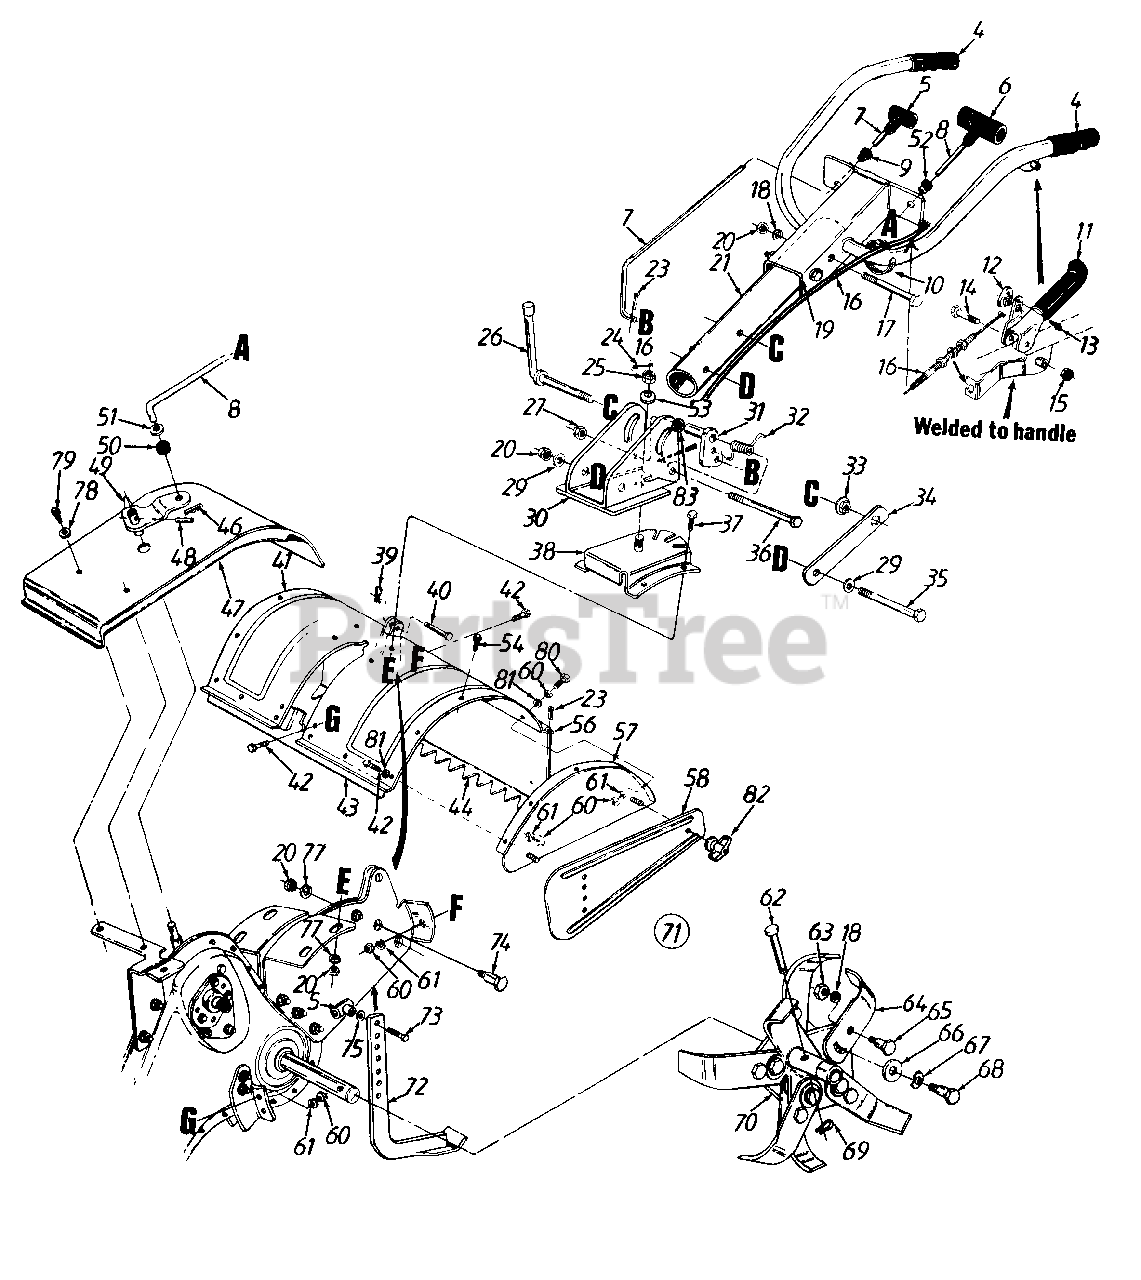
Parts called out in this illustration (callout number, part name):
4	Handle Grip
5	Small "T" Knob
6	Large "T" Knob
7	Clutch Rod
8	Control Rod 37" Lg.
9	Snap On Bushing 3/8" Dia.
10	Cable Tie-Self Clinching
12	Barrel Cable Hold Down
13	Hex B-Tap Scr. #10 x .44" Lg.
14	Hex Bolt 3/8-24 x 2.25" Lg.
15	Hex Jam L-Nut 3/8-24 Thd.
16	Clutch Control Cable 46" Lg.
17	Hex Bolt 3/8-16 x 3.00" Lg.
18	L-Wash. 3/8" I.D.- H.D.
24	Cotter Pin 3/32" Dia. x 1.25" Lg.
25	Hex Slotted Nut 5/8-18 Thd.
26	Handle Adj. Crank
27	Hex Cent. L-Nut 3/8-16 Thd.
29	Bell-Wash..4" I.D. x .87" O.D.
32	Spring Handle Adj. (Torsion)
33	Hex Flange Nut 3/8-24 Thd.
34	Bracket Hex Nut Retainer
35	Hex Bolt 3/8-16 x 3.25" Lg.
36	Hex Bolt 3/8-16 x 3.00" Lg.- Gr. 8
37	Hex Bolt 3/8-16 x 1" Lg.
40	Clevis Pin .375" Dia.
43	Bracket Reinforcement - 18"
46	Intern. Cotter Pin 5/16" Dia.
49	Shifting Crank Ass'y.
50	Rubber Washer.33" I.D.
51	Fl-Wash. .4" I.D. x 1.25" O.D.
52	Snap On Bushing 1/2" Dia.
53	Bell-Wash. .63" I.D. x 1.25"
54	Hex Wash. Tap Scr.
56	Tiller Flap Rod
60	Hex Nut 5/16-18 Thd.
61	L-Wash. 5/16" I.D.
62	Clevis Pin .375" Dia.
63	Hex Nut 3/8-24 Thd.
65	Shld. Bolt 1/2" Dia. x .175
66	Fl-Wash. .51" I.D. x 1.50"
67	Bell-Wash. .515" I.D. x 1.14"
68	Shld. Bolt 1/2" Dia. x .320
69	Intern. Cotter Pin
73	Hex Bolt 3/8-16 x 1" Lg.
74	Shld. Bolt 1/2" I.D. x .62" Lg.
75	Fl-Wash. 3/8" I.D. x 5/8" O.D.
77	L-Wash. 3/8" I.D.
78	Fl-Wash. .281" I.D. x .62"
79	Hex Wash. Self-Tap Scr. 1/4-20 x .50" Lg.
80	Hex Bolt 5/16-18 x 11/4" Lg.
81	Cap L-Nut 5/16-18 Thd.
82	Plastic Knob 5/16-18 Thd.
83	Fl-Wash. .406" I.D. x .875" O.D.
